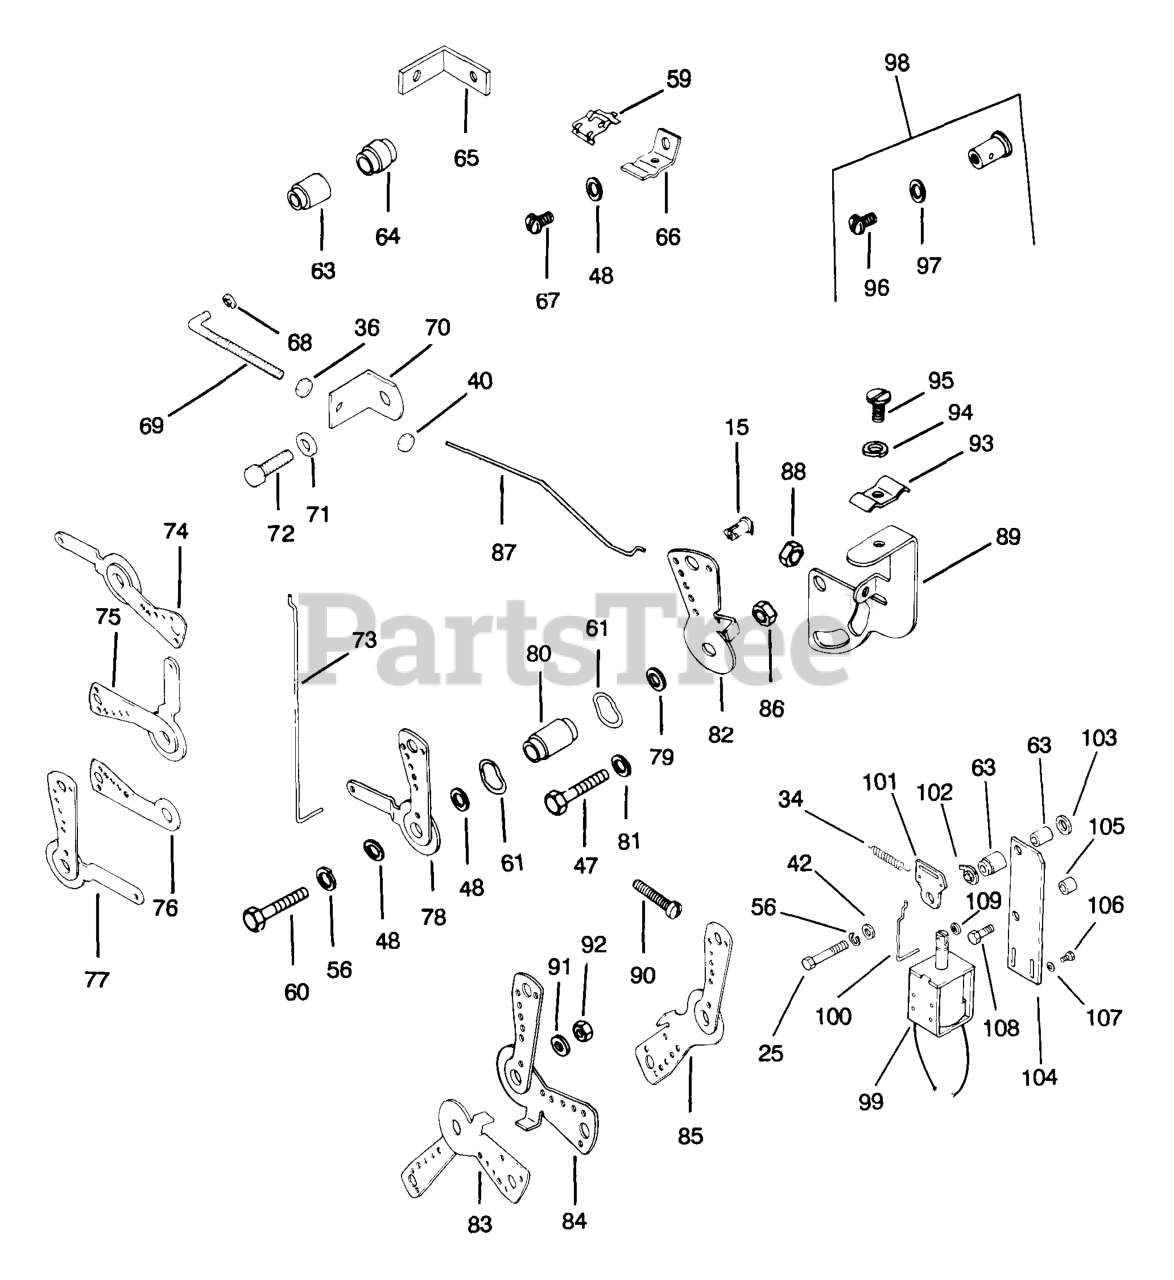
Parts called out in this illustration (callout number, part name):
48	WASHER, FLAT 1/4" (O.D. 1/2")
61	WASHER, SPRING 11/32"
67	SCREW, SEMS 1/4-20-1/2"
73	LINKAGE
77	LEVER - DISCONTINUED
80	SPACER
84	LEVER - DISCONTINUED
88	NUT, MACH SCREW #8-32 GRD 2 USE 25 100 16-S
90	SCREW, SPECIAL
92	NUT, 1/4-20 GRADE 2 USE 25 100 20-S
93	CLAMP, DUAL CONDUIT
95	SCREW, WSH HD TAP #10-24X3/4" USE 25 086 97-S
96	SCREW - USE 41 086 20
97	WASHER, FLAT 1/4"
98	KIT, CLAMP
